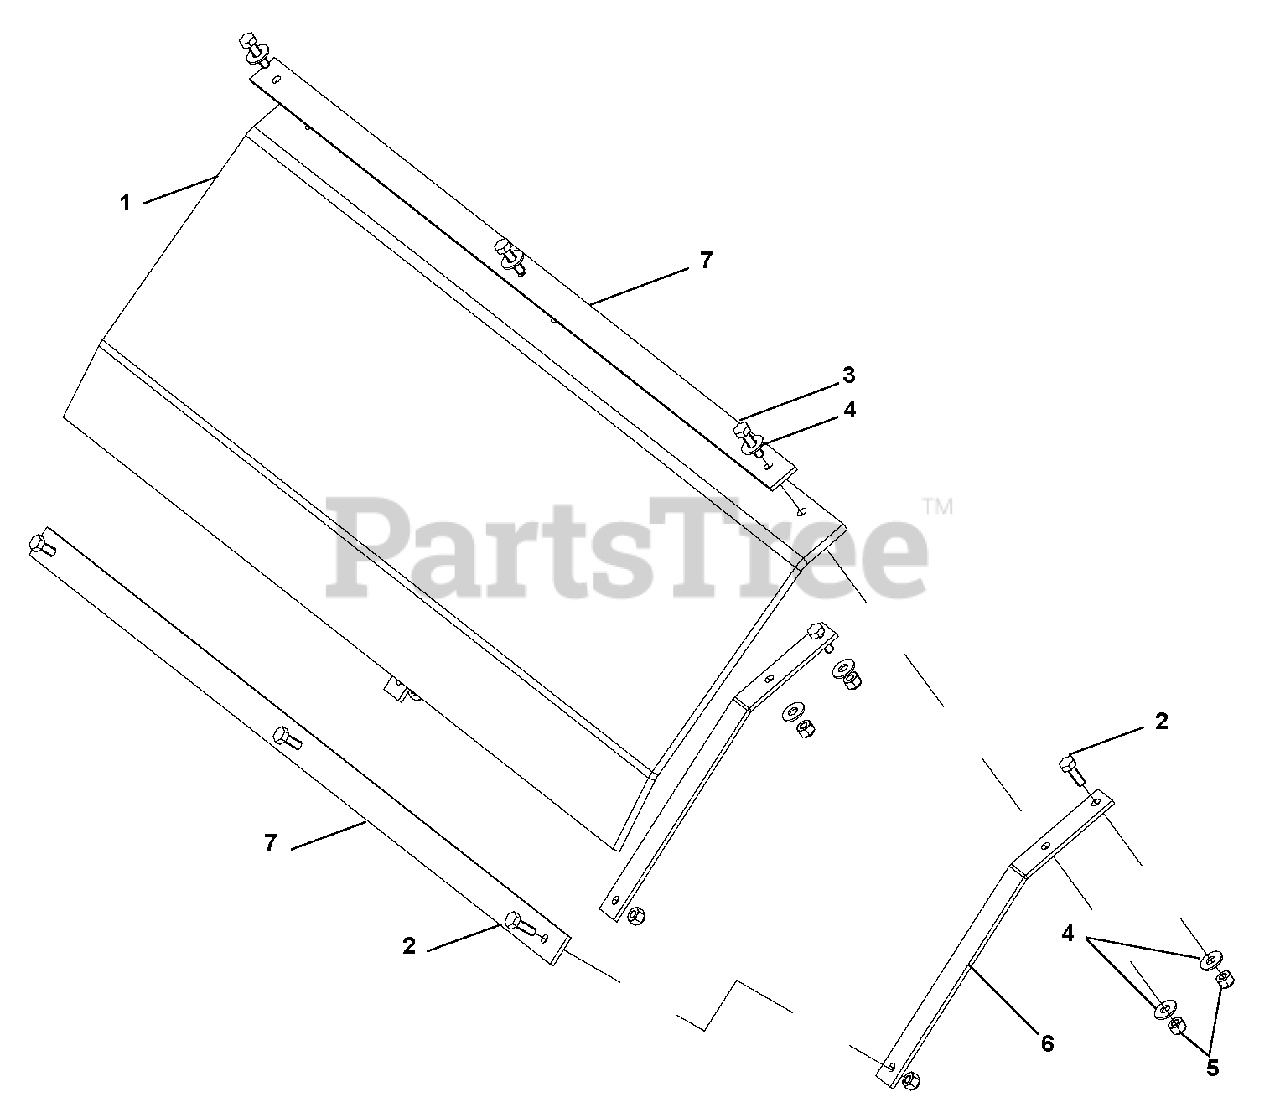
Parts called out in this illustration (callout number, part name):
1	Deflector, 36"
2	Bolt, Hex .25-20 X 1.25
3	Bolt, Hex .25-20 X 1.50
4	Washer, Flat Steel .312 X .734 X .065
5	Nut, Locking, Nylon .25-20
6	Strap, Deflector Support
7	Strap, Support
